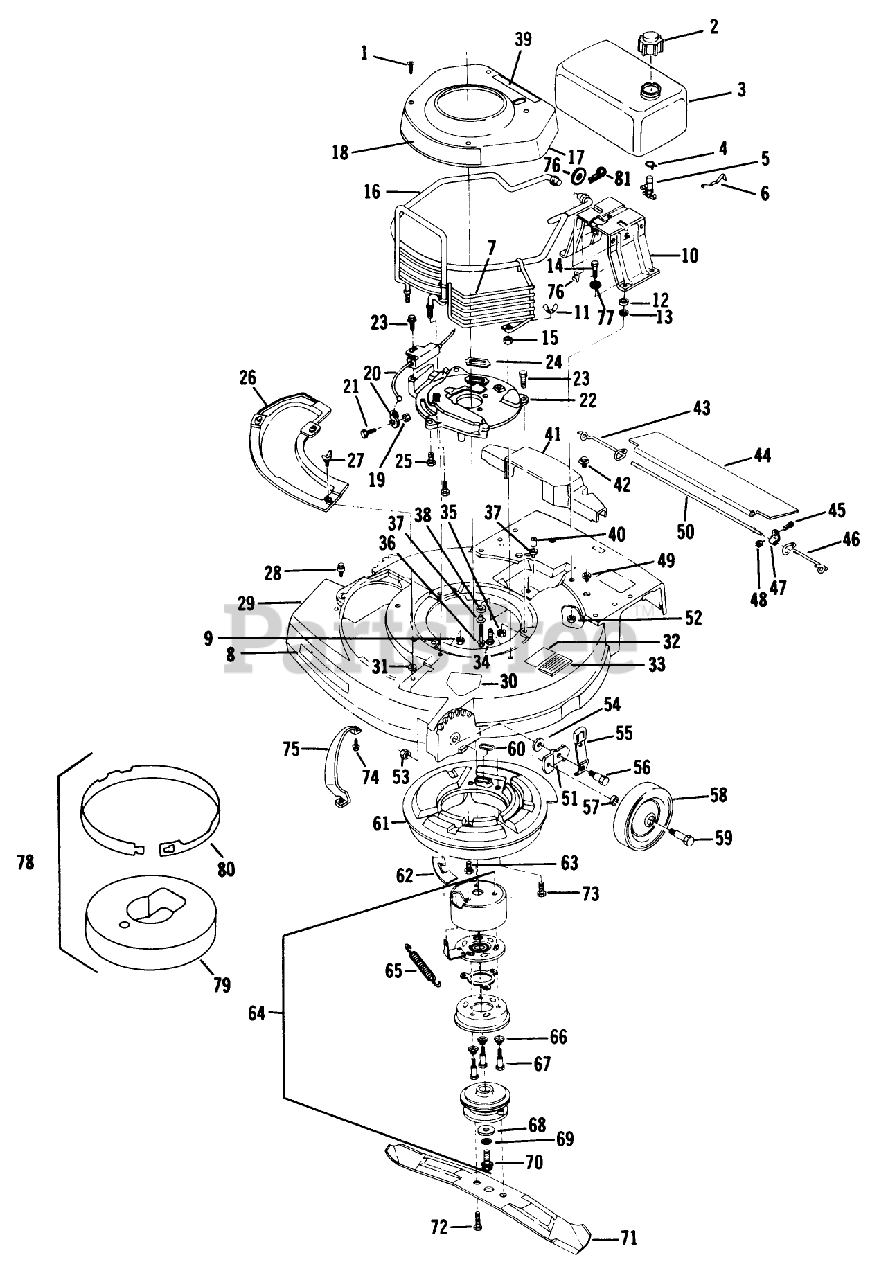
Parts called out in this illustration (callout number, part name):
1	SCREW - SELF TAPPING
2	FUEL CAP & INSERT
4	CLAMP - HOSE S
5	VALVE&SCREEN SM
6	SPRING
9	NUT-LOCK F
13	WASHER
14	BOLT PIONEER
15	LOCKNUT E
17	SHROUD S
19	LOCKNUT E
23	SCREW-HH
25	SCREW V
27	WING SCREW LAWRE
33	PAD FOOT
34	Screw
35	NUT-LOCK F
37	SPACER ECK PRES
38	GROMMET
40	SPACER
41	COVER
42	SCREW SEMS TRM HEX HD
43	SPRING;TRAILING SHIELD RH
44	SHIELD
46	SPRIG T/SHLD ASOC
47	CLAMP ROD KMC
48	LOCKNUT E
50	ROD 21" ADVANCE
52	LOCKNUT E
53	LOCKNUT
54	WASHER
56	BOLT
57	WASHER WROUGHT
58	WHEEL & TIRE ASSY
59	BOLT-SHOULDER
60	SEAL
63	SCREW
65	SPRING
67	SCREW,SHOULDER SM
68	WASHER
75	BAR-TOE
76	WASHER SPRING LAR
77	WASHER
81	HAIR PIN
